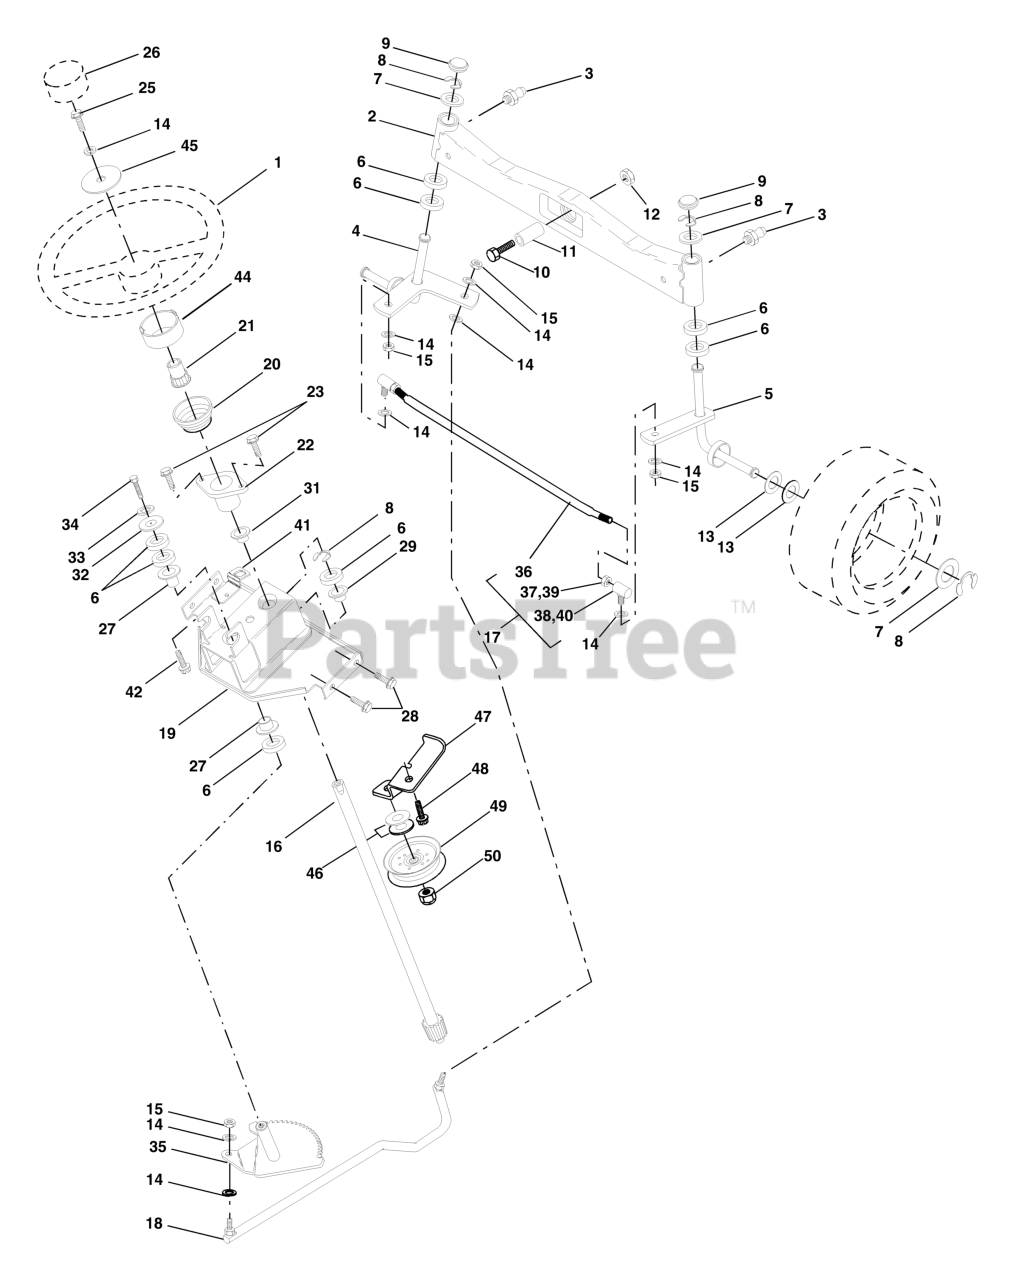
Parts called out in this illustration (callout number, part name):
1	STEERING WHEEL
2	AXLE.FRONT.CAST.MACHINE.W/ZERK
3	ZERK M
4	SPINDLE ASSY LH
5	SPINDLE ASM RH
6	THRUST WASHER
9	CAP.SPINDLE.BLACK
10	Bolt, Fin Hex 5/8-11 x 2-3/4
11	TUBE, PIVOT AXLE
12	NUT-LOC,FLANGE LT
14	WASHER, LOCK 3/8
15	GRIPCO NUT
16	SHAFT ASM, STEERING
17	ROD ASSY/TIE BALL
18	DRAGLINK, BALL JOINT (3SPG1401
19	SUPPORT ASM., STEERING VGT
20	BOOT, STEERING
21	STEERING WHEEL ADAPTOR
22	BUSHING, STRG. BLK
23	SCREW.TT.#10-32X.5.3/8.FLANGE
25	BOLT
26	CAP.WHEEL.STEERING.GREY
27	BRNG T
28	SCREW, 3/8-16X3/4
29	BEARING-FLANGE GT
31	BUSHING.NYLINER.
33	WASHER.LOCK.HVY.HLCL.SPR.5/16
34	BOLT.FIN.HEX.5/16-18X3/4
35	GEAR.ASM.SECTOR.
36	TIE ROD
38	JOINT
41	BRACKET INTERLOCK
42	Screw 5/16-18 x 1/2
44	EXTENSION STEERING PREMIUM
45	Washer 13/32 x 1-1/20 x 11 Ga.
47	BRACKET ASM, IDLER STATIONARY
48	SCREW 3/8-16X3/4
49	PULLEY.IDLER.FLAT.46.PR.DR.
50	NUT LOCK FLG 3/8-16 UNC
